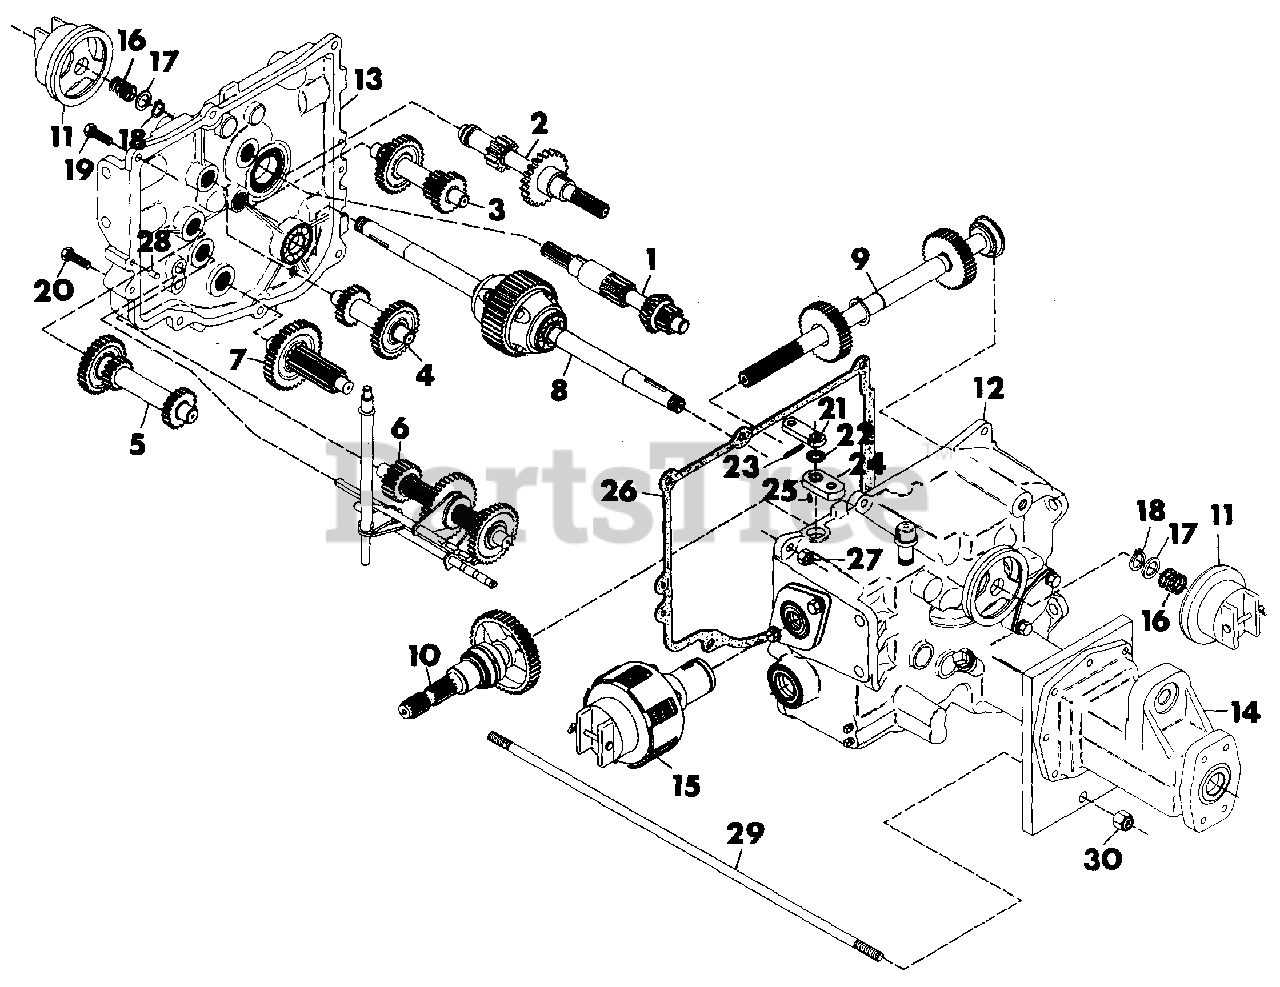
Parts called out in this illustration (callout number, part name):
1	NUMBER 1 SHAFT - FORWARD CLUTCH
2	NUMBER 2 SHAFT - REVERSE CLUTCH
3	NUMBER 3 SHAFT - 3RD AND 4TH GEAR
4	NUMBER 4 SHAFT - IDLER
5	NUMBER 5 SHAFT - 1ST AND 2ND GEAR
6	NUMBER 6 SHAFT - BRAKE/SLIDING GEAR
7	NUMBER 7 SHAFT - PINION/FINAL DRIVE
8	NUMBER 8 SHAFT - DIFFERENTIAL ASM.
9	NUMBER 9 SHAFT - PTO CLUTCH SHAFT
10	NUMBER 10 SHAFT - PTO DRIVE ASM.
11	NUMBER 11 - FWD-REV CLUTCH ASM.
12	NUMBER 12 - TRANSMISSION CASE ASM.
13	NUMBER 13 - TRANSMISSION COVER ASM.
14	NUMBER 14 - AXLE HOUSING
15	NUMBER 15 - PTO CLUTCH ASSEMBLY
16	SPRING, COMP. TYPE 1.0X.80X36 LB/IN
17	RACE, BEARING THRUST .752X1.240X.03
18	RING, RETAINING .750 SHAFT
19	BOLT, HEX 3/8-16X1.50
20	BOLT, HEX 3/8-16X2.25
21	ARM, SHIFTER
22	WASHER, FELT
23	PIN, SPRING .187X1.000
24	ARM, SHIFTER
25	KEY, WOODRUFF .125X.375 HARD
26	GASKET, TRANSMISSION COVER
27	NUT, LOCK 3/8-16
28	PIN, DOWEL .375X.625
29	ROD, STRUT
30	NUT, LOCK 1/2-13
